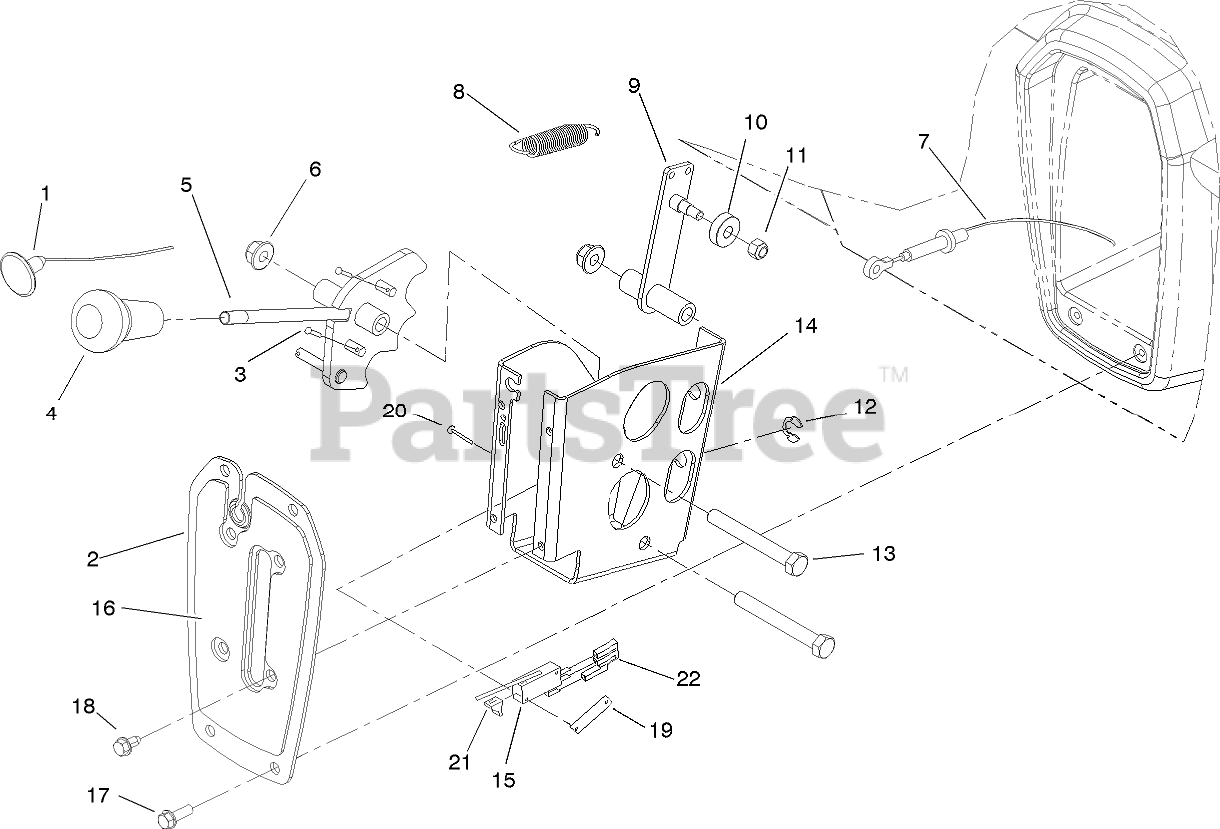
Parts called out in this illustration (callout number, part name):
1	CABLE-CHOKE
2	PLATE-SHIFTER
3	PIN-COTTER
4	KNOB-GRIP, SOFT
5	LEVER-SHIFTER
6	NUT-HF, NI
7	Cable-Shift
8	SPRING-RETURN, PEDAL
9	DETENT
10	BEARING-BALL
11	NUT-LOCK, NI
13	SCREW-HH
14	BRACKET-SHIFT
15	SWITCH-MICRO
16	DECAL-SHIFTER
17	SCREW-HWH
18	SCREW
19	NUT-SPEED
20	SCREW-SPH
21	PLUNGER-SEAL
22	HARNESS-JUMPER, SHIFT
